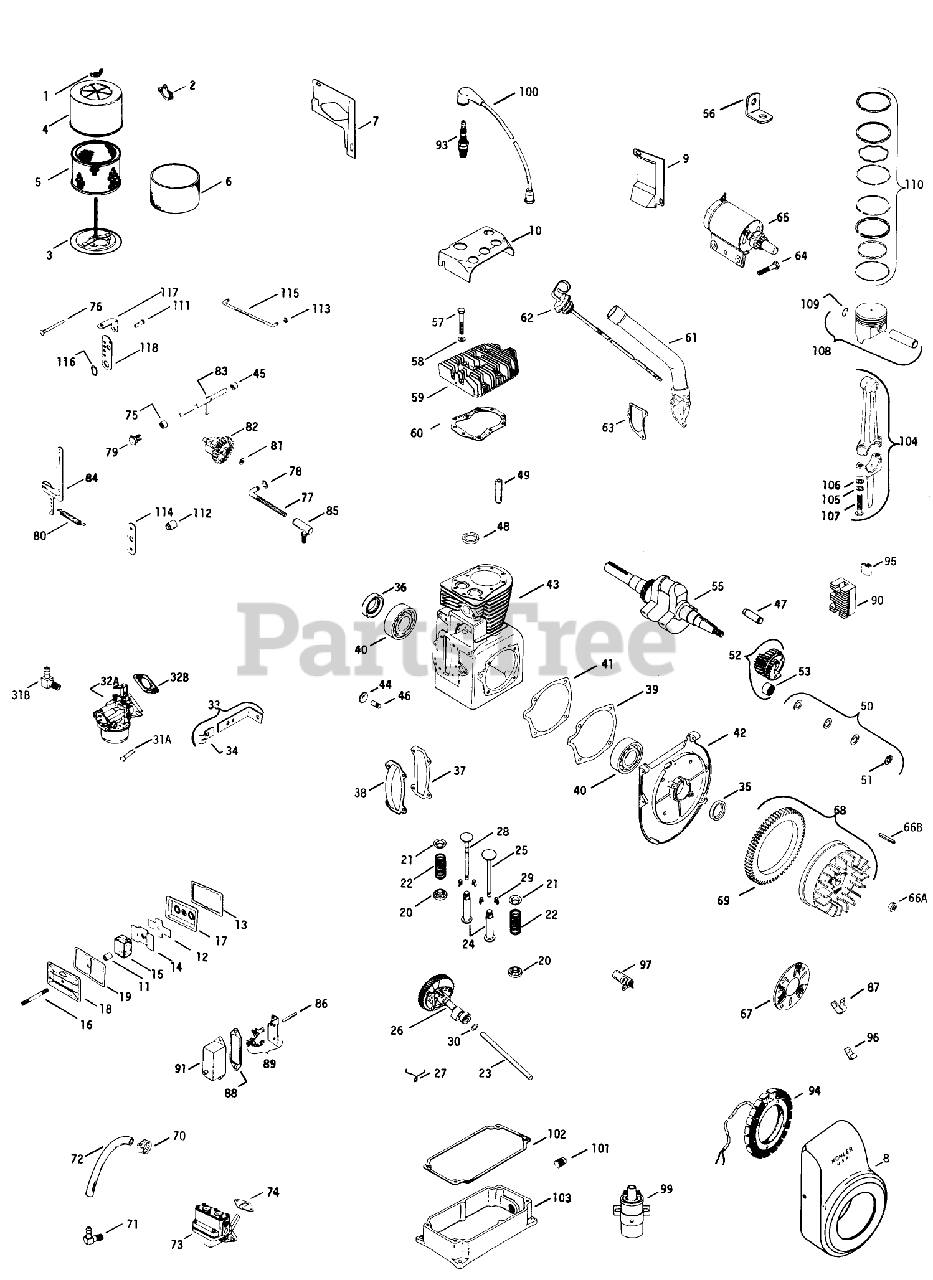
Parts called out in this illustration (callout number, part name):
1	Nut-Wing
2	Gasket-Air Horn
3	Base-Air Cleaner
4	Cover-Air Cleaner
5	Element
6	Element
7	BaffLe side air
8	Housing-Blower
9	Baffle, cylinder
10	Baffle, head
11	Seal
12	Reed
13	Gasket
14	Baffle breather
15	Filter Breather
16	Stud, valve cover
17	Plate
18	Cover valve
19	Gasket
20	Rotator
21	Retainer-Spring
22	Spring
23	Pin (Service)
24	Tappet
25	Valve-Intake
26	Camshaft-assembly
27	Spring-Actuating
28	Valve exhaust
29	Keeper, Valve
30	Spacer
31A	Screw sitd. hd.
31B	Elbow
32A	Carburetor-assembly
32A	Repairkit
32B	Gasket
33	Bracket, choke
34	Clip
35	Seal, Front OiI
36	Seal rear oil
37	Gasket
38	Cover
39	Gasket
40	Ball Bearing
41	Gasket
42	Plate Bearing
43	Block, cylinder-assembly (Use 45_782_02 Miniblock)
44	Plug
45	Bearing
46	Shaft-Govemor
47	Shaft
48	Insert
49	Guide Valve
50	Kit-Spacer
51	Retainer
52	Gear
53	Bearing,needle
55	Crankshaft
56	Lift Cable
57	Screw, H.C. 3/8-16 x 1-1/2
57	Screw-H.C.
58	Washer
59	Head, cylinder
60	Gasket, head
61	Tube, fill
62	Dipstick
63	Gasket
64	Screw
65	Starter-assembly
65	Kit, Brush Spring
65	Washer
66A	Nut
66B	Key
67	Screen grass
68	Flywheel-assembly
69	Gear Ring
70	Clamp
71	Elbow
72	Line Fuel
73	Pump, fuel
74	Gasket, pump
75	Spacer
76	Pin-GovemorStop
77	Rod ball joint
78	Retainer Rod
79	Bushing
80	Spring-Governor
81	Washer
82	Gear, Governor
83	Shaft, Governor
84	Lever, Governor
85	Ball Joint
86	Rod, breaker
87	Clip
88	Gasket, Cover
89	Breaker
90	Regulator
91	Cover breaker
93	Plug, spark
94	Stator
95	Connector
96	Clip
97	Condenser
99	Coil
100	Kit, Hi-Tension
101	Plug
102	Gasket
103	Base, oil pan
104	Rod, conn.-assembly Std.
104	Rod conn.-assem. (.010 U.S.)
105	Washer
106	Washer
107	Screw, connecting rod
108	Piston-assembly (Std.)(Includes pin retainers)
108	Piston-assembly (.003)(Includes pin retainers)
108	Piston-assembly (.010) (Includes pin retainers)
108	Piston-assembly (.020)(Includes pin retainers)
108	Piston-assembly (.030) (Includes pin retainers)
109	Pin, Retainer
110	Ring set-Std. .003
110	Ring set-.010
110	Ring set-.020
110	Ring set-.030
111	Clamp, swivel wire
112	Spacer
113	Retainer Rod
114	Bellcrank
115	Rod, throttle
116	Washer
117	Spacer
118	Bracket
